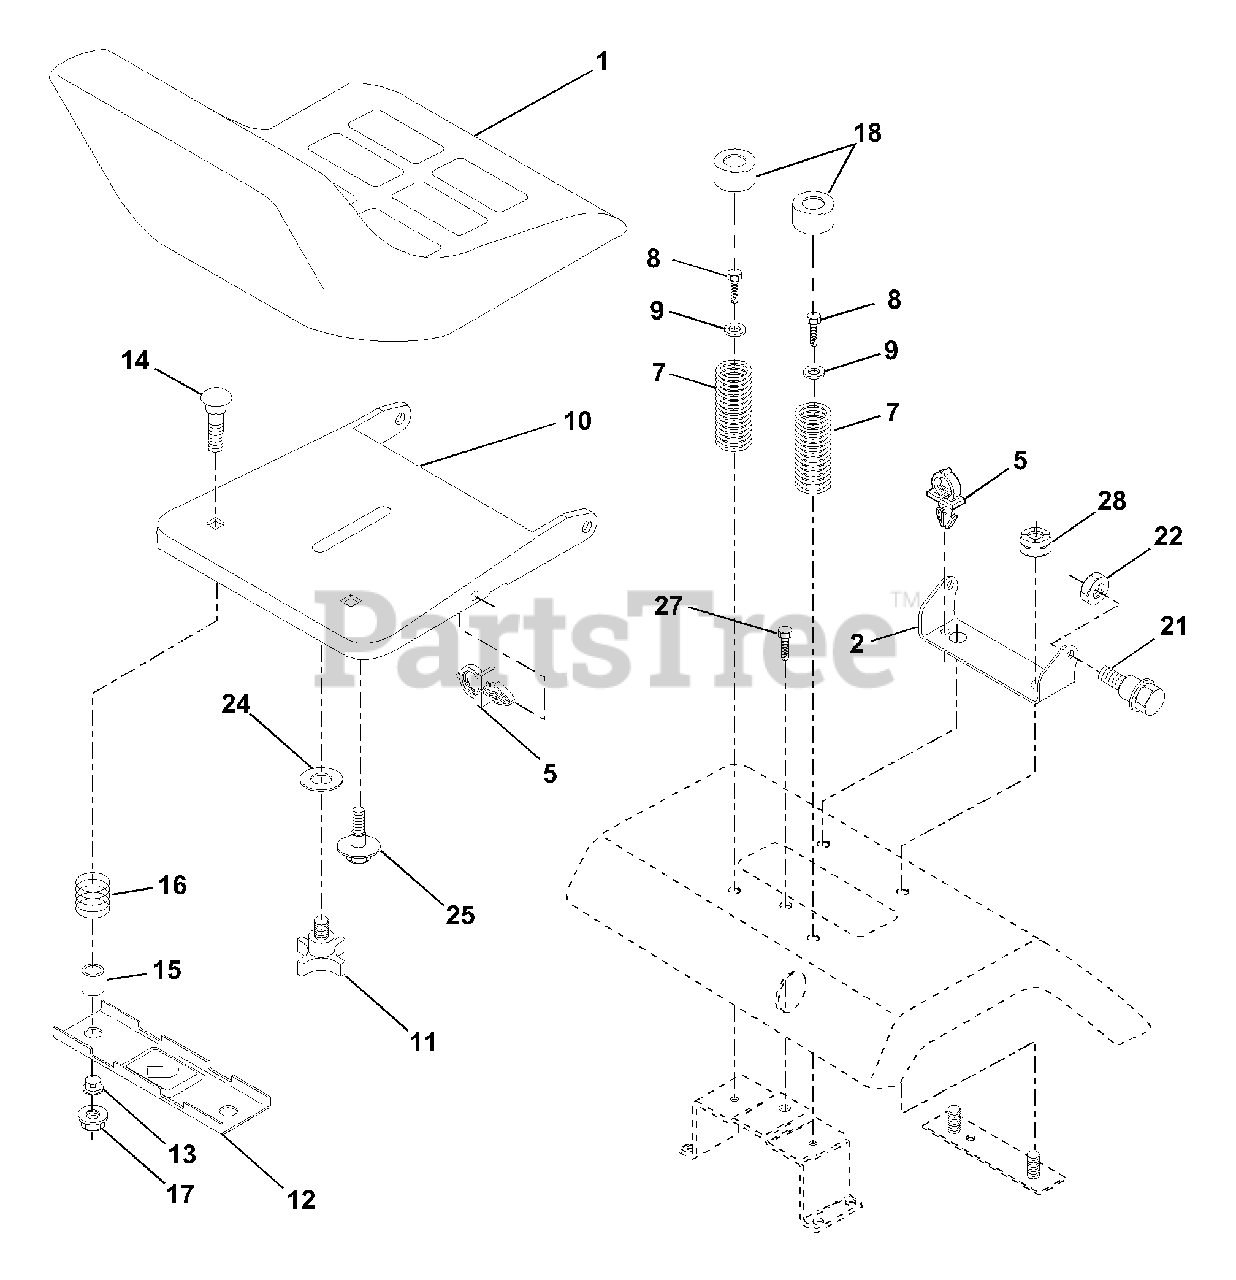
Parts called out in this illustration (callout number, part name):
1	Seat V-550 Gry/blk Std
2	Bracket Pivot Seat
5	Clip, Push-In
7	Spring Seat Cprsn 2 250 Blk Zi
8	Screw Hwsh Thdrol 5/16-18 x 1/2
9	Washer 13/32 X 1 X 14 Ga
10	Pan Seat
11	Knob Seat 1/2-13unc Blk
12	Bracket Mounting Switch
13	Bushing Snap Blk Nyl 50 Id
14	Bolt Rdhd Sht Nk 1/4-20x1-3/8
15	Spacer Split 28x 88 Yel Zinc
16	Spring Cprsn 1 310 Blk Pnt
17	Nut Lock 1/4 Lge Flg Gr 5 Zinc
18	Cap Spring Seat
21	Bolt Shoulder 5/16-18 Unc Blkz
22	Nut Crown Lock 5/16-18
24	Washer 17/32 X 1-3/16 X 12 Ga
25	Bolt Shoulder 5/16-18 X 62
27	Screw Thdrol 3/8-36 x 1/2
28	Nut, Crownlock 3/8-16 UNC
